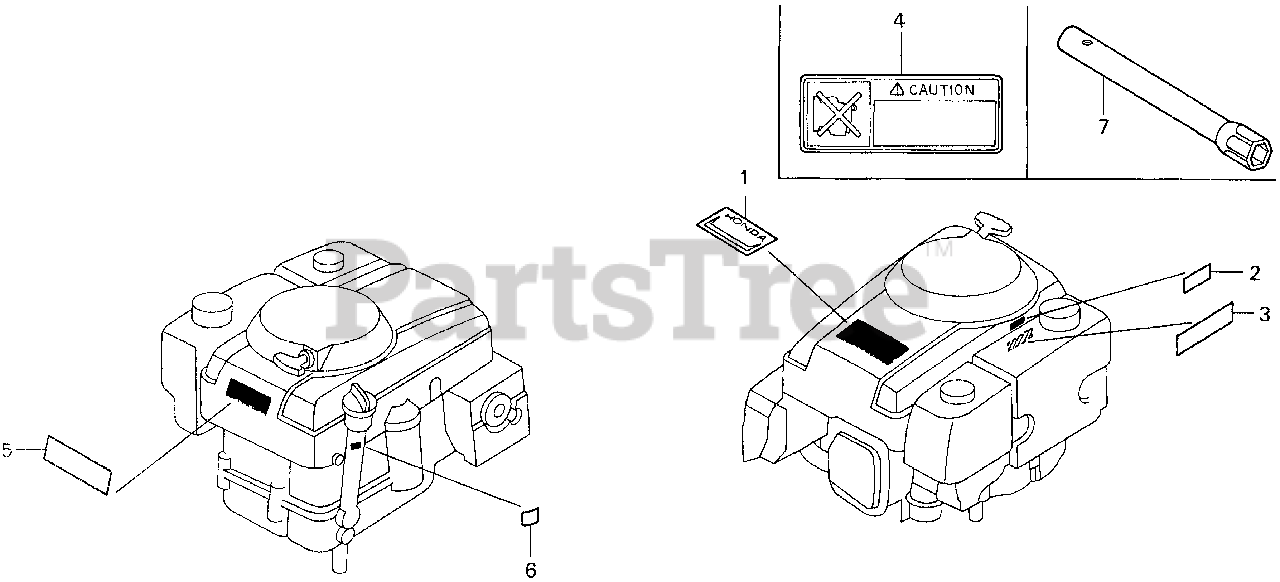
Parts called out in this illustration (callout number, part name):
1	MARK, TOP COVER EMBLEM (13.0)
2	LABEL, FUEL CAUTION
3	LABEL, HONDA NAME
3	LABEL, NAME (HONDA)
4	LABEL, MAINTENANCE CAUTION
5	LABEL, CAUTION
6	MARK, TYPE (DP23)
7	WRENCH, BOX (P21)
